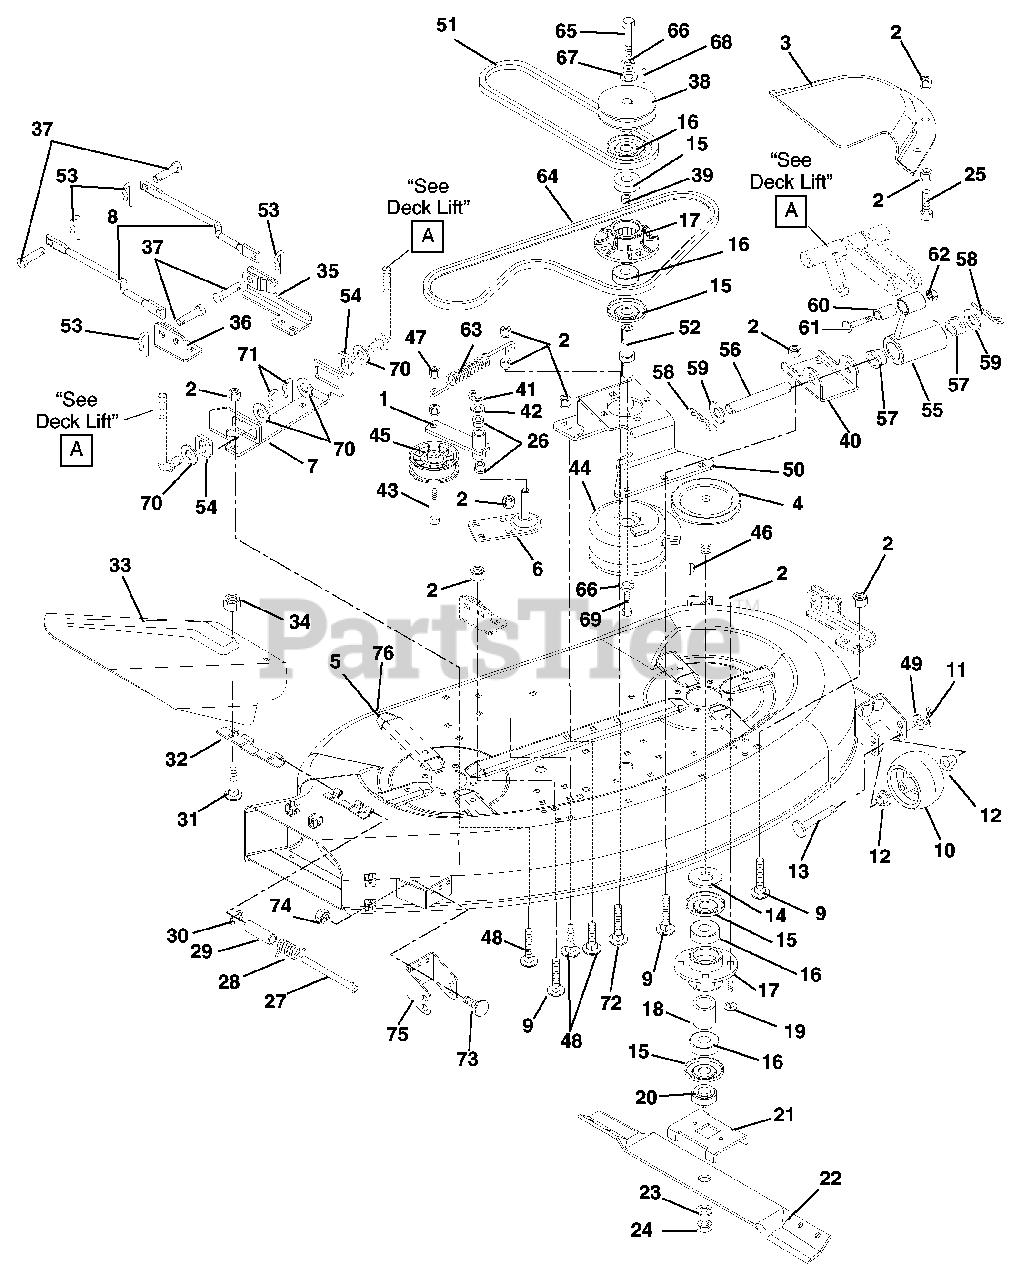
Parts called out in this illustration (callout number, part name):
1	WLDMT-IDLER
2	NUT-LK-TOP-FLG .38-16 BLKZC
3	COVER, 40" DECK SHEAVE
4	L. SPINDLE SHEAVE
5	WLDMT - 40" DECK RAW
6	BKT-IDLER MOUNT
7	BRKT, REAR HANGER (40" DECK)
8	LINK-STABILIZER 40" DECK BLK
9	BLT-RDHDSQNK .38-16X1.00 G5BZ
11	PIN-HAIR INT .08X.18X1.18 YWZC
12	BSHG-FLG .372X.500X.312X.625NY
13	PIN-CLEV .371X3.25 YWZC
14	WSHR-FL-STL .755X1.25X.125 YZ
15	BEARING SLINGER
16	BRG-BALL .750X1.781X.61
17	SPINDLE HOUSING
18	SPACER .753X1.000X1.140
19	@BLT-RDHDSQNK .38-16X1.00 G5YZ
20	RETAINER HUB
21	BLADE TRAY 48
23	@WSHR-LK .75X.188 REG YWZC
24	NUT-JAM .75-10 YWZC
25	@BLT-HEX .38-16X1.00 GR5 YWZC
26	BSHG-FLG.500X.625X.312X.750NY
28	SG-TORS .095X.50X 1.0
29	BSHG-SLV .334 X .502 X 1.437
30	RG-RTNG-EXT .312X.025
31	BLT-RDHDSQSHNK.25-20X.50 YWZC
32	HINGE PLATE
33	40IN. CHUTE DEFLECTOR
34	NUT-LK-FLG .250-20 PL BLK
35	BKT-DECK LINK (LH)
36	WLDMT DECK LINK BKT (RH)
37	PIN-CLEV .494X1.00 BLKZC
38	PULLEY, 40" DECK INPUT
39	SPACER .753X1.000X1.140
40	BRKT, FRONT HANGER
41	RG-RTNG-EXT .500X.042 (E)
42	WSHR-FL-STL .505X.880X.072 YWZ
43	@BLT-HEX .38-16X2.25 GR5 YWZC
44	ELECTRIC CLUTCH/BRAKE (3.4AMP)
45	IDLER-FLAT 3.00X.38
46	KEY-WDRF .188X.625X.31 SAE9MOD
47	@NUT-SPNLK-FLG .375-16 YWZC
48	BLT-RDHDSQNK .38-16X.75 G5BZ
49	BLT-RDHDSQNK .31-18X1.0 SHTYZ
50	BKT SPINDLE HSG MOUNT
51	V-BELT, HA-WRAPPED
52	SHAFT, 40" DECK INPUT
53	CLIP, SPRING
54	SLIDER, HANGER BRKT
55	LINK, FRONT LIFT (40" DECK)
56	PIVOT, FRONT LIFT LOWER
57	BUSHING-1"X.75"X1"
58	PIN, HAIR #6
59	WSHR-FL-STL .700X1.47X.134 YWZ
60	BSHG-SLV .500X.750X1.560
61	BLT-RDHDSQSHNK .50-13X2.75 YZ
62	NUT-LK-CTR-JAM .50-13 YWZC(ND)
63	SG-TENS .095X.500X5.5 WLD60 YZ
64	V-BELT, HA-RAW EDGE
65	BLT-HEX .38-16X1.00 YZ GR8
66	WSHR-LK .375X.115 HVY YWZC
67	WSHR-FL-STL .406X1.375X.135 YZ
68	KEY-SQ .187 X .50 X .187
69	BLT-HEX .38-24X2.0 YWZC
70	WSHR-FL-STL .518X2.0X.105 YWZC
71	PIN, HAIR, EXT - #16 YWZC
72	@BLT-RDHDSQNK .38-16X2.00 G5YZ
73	@BLT-RHDSSQNK .31-18X.62 G5YZ
74	@NUT-SPNLK-FLG .312-18 YWZC
75	ROLLER CLEVIS
76	KIT, 40" DECK ASSY SERVICE
